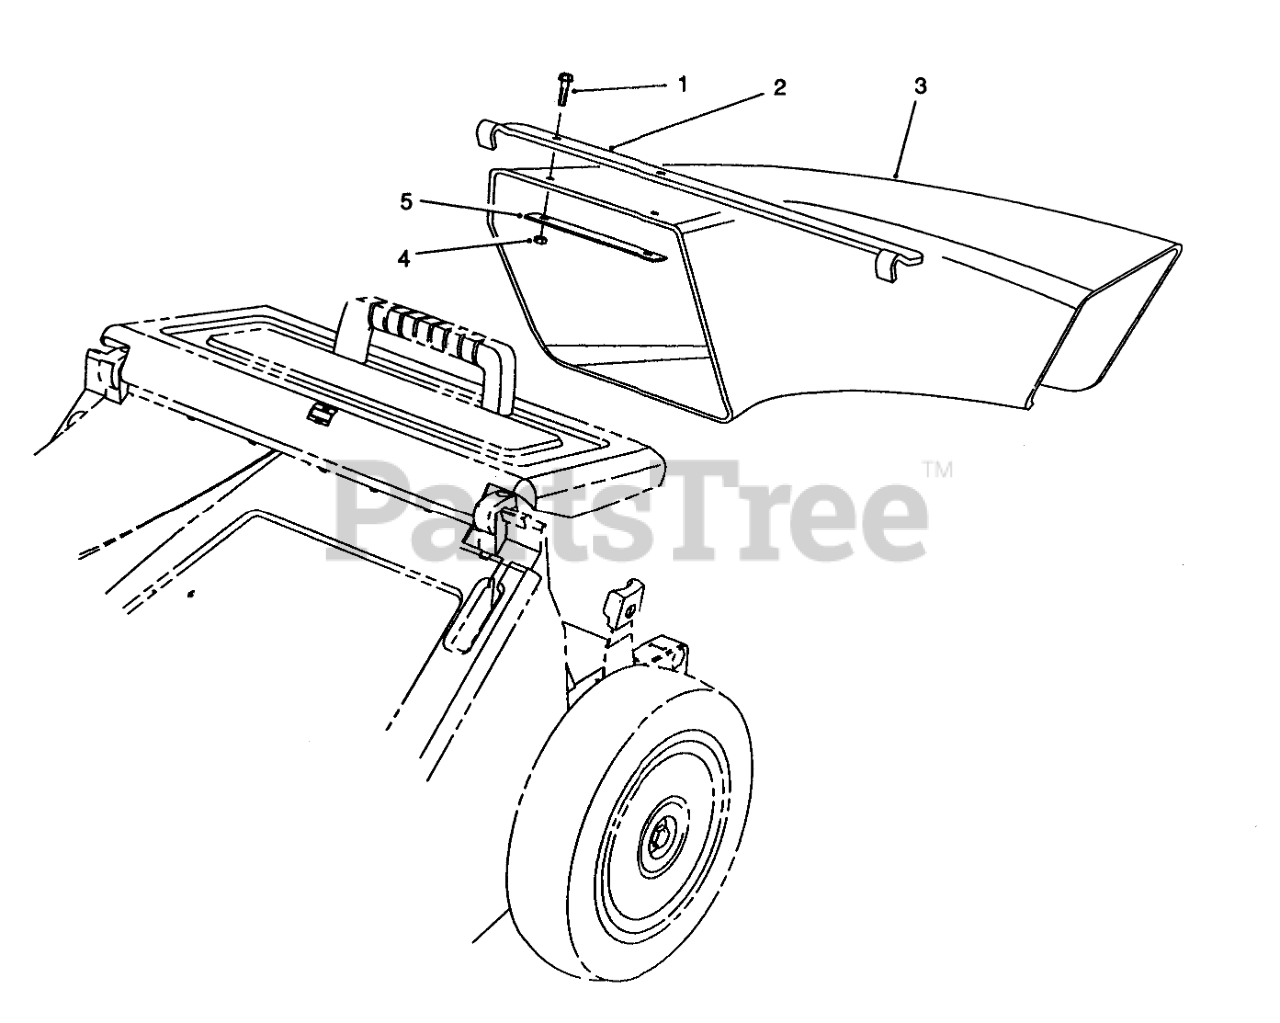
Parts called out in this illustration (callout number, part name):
1	SCREW-HWH
2	CHUTE HANGER BRACKET
3	Chute-Discharge
4	NUT-LOCK, NI
5	STRESS PLATE
